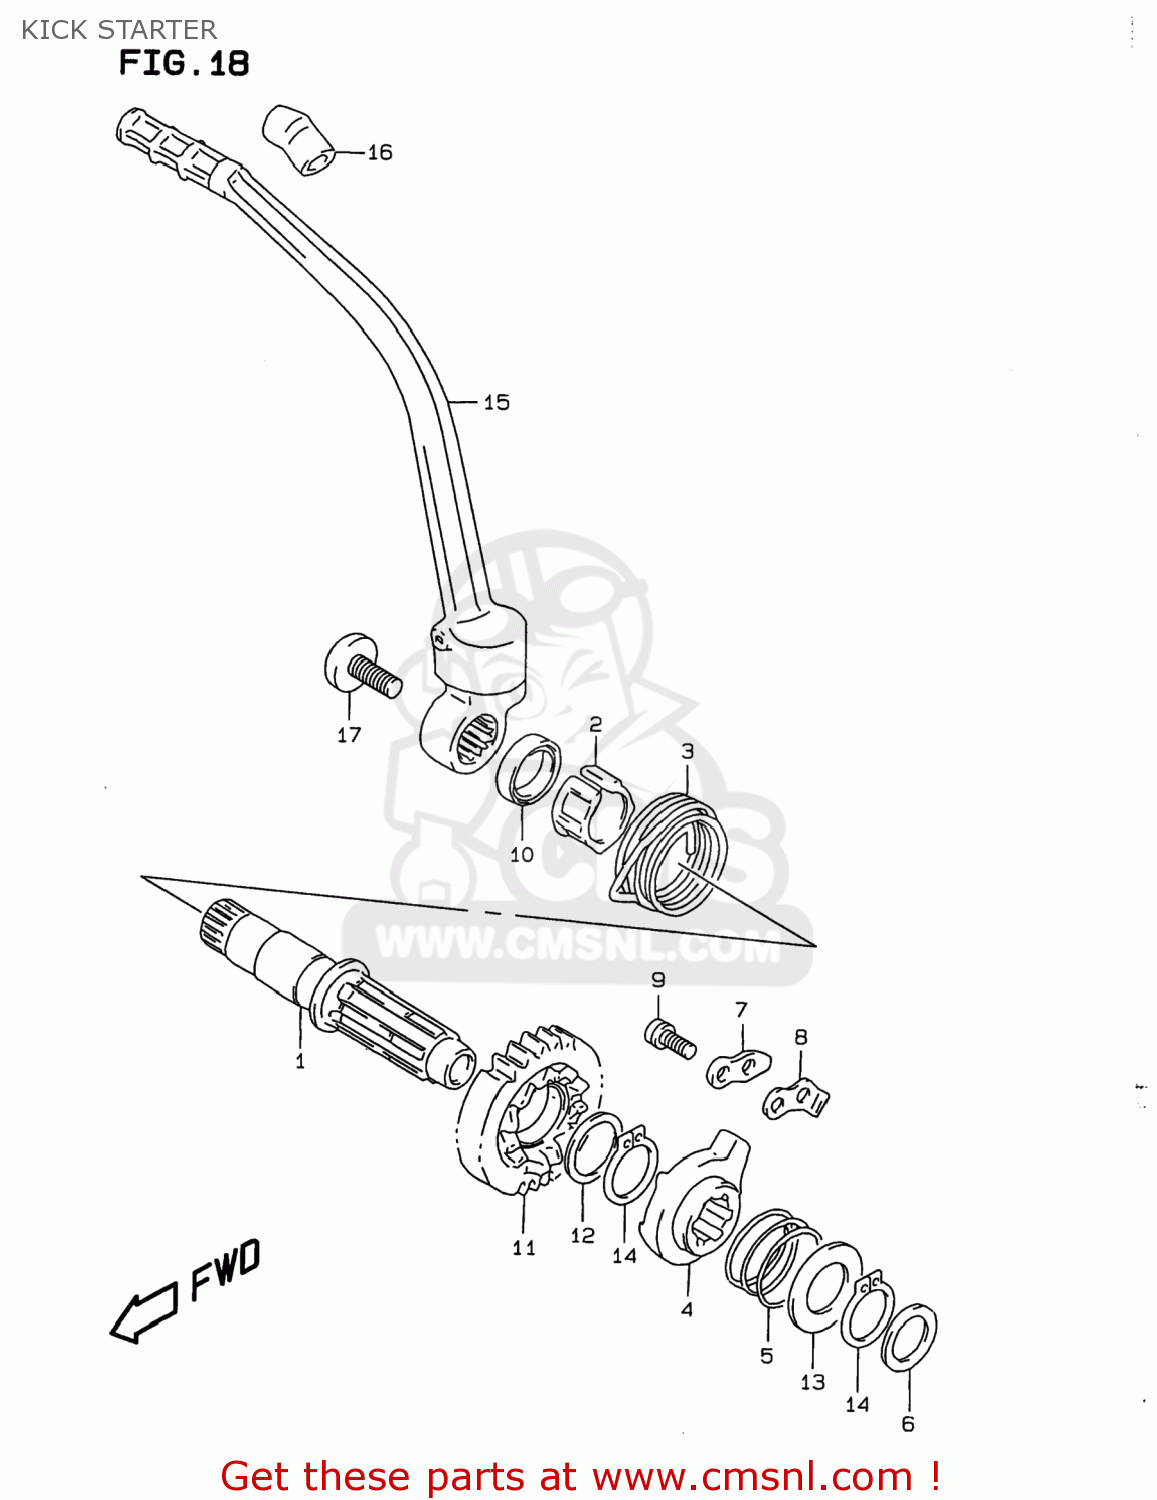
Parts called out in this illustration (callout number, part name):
1	SHAFT,KICK STARTER
2	GUIDE,KICK STARTER SFT SPRING
3	SPRING
4	STARTER,KICK
5	SPRING
6	SHIM(17X26X1)
7	GUIDE,KICK STARTER
8	STOPPER,KICK STARTER
9	BOLT,KICK START STOPPER
10	SEAL,OIL(20X27X6)
11	GEAR,KICK STARTER(NT:23)
12	SHIM(22X28X1)
13	SHIM(22X36X1)
14	CIRCLIP
15	LEVER ASSY,KICK STARTER
16	COVER,KICK STARTER LEVER
17	BOLT(8X14)
